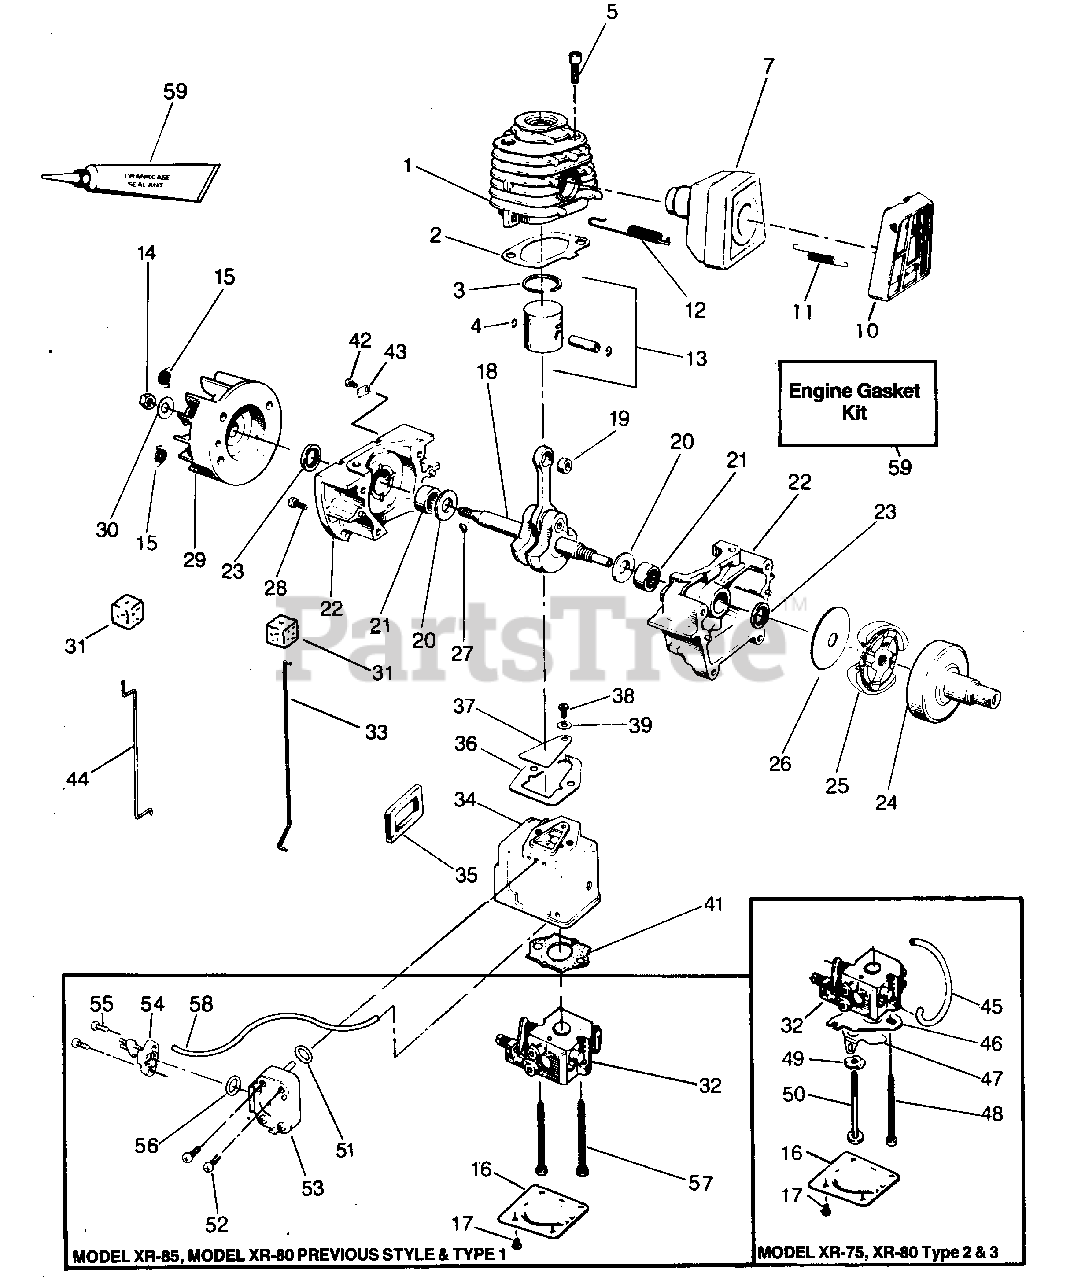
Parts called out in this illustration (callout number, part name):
1	Cylinder
1	Model XR-80,XR-85
1	Model XR-75
2	Gasket - Cylinder
3	Piston Ring
3	Model XR-85, XR-80 Type 1 & 2
3	Model XR-80 - Type 3
3	Model XR-75
4	Retainer - Wrist Pin
5	Screw #1/4 - 20 x 3/4" - Hex Soc. Hd. - Cylinder
10	Guard - Muffler
11	Spring - Muffler Guard
12	Spring - Muffler Attachment
13	Piston Kit (Inc. #3, 4 & Pin)
13	Model XR-85,XR-80 Previous Style & Type 1 & 2
13	Model XR-80 - Type 3
13	Model XR-75
14	Nut - Flywheel
15	Spring - Starter Dog
16	Cover - Carburetor Case
16	Model XR-80,XR-85
17	Screw - #8 - 18 x 9/16" - Pan Hd Carburetor Case Cover
18	Crankshaft & Rod Ass'y.
18	Model XR-75,XR-85, XR-80 Previous Style & Type 1, 2
18	Model XR-80 - Type 3 Only
19	Bearing - Wrist Pin
19	Model XR-75,XR-85, XR-80 Previous Style & Type 1, 2
19	Model XR-80 - Type 3 Only
20	Washer - Thrust - Crankcase
21	Bearing - Crankshaft
22	Crankcase Ass'y. (Inc. #21, 23 & Qty. 1 of #28)
23	Seal - Crankcase
24	Drum & Coupling Assembly
25	Kit - Clutch Assembly (Inc. Clutch Washer) - See Service Ref. 1 & 7
26	Kit - Clutch Washer
27	Key - Flywheel
28	Screw - #10 - 24 x 5/8" Fil. Hd. - Crankcase
29	Flywheel Assembly (Inc. #15)
30	Washer - Flywheel
31	Boot - Throttle/Choke Wire
32	Carburetor (See Service Ref. 2 - for Model XR-75 only)
33	Throttle Wire
33	Model XR-75, XR-80 Type 2 & 3
33	Model XR-85, XR-80 - Previous Style & Type 1
34	Carburetor Case
34	Model XR-85, XR-80 Previous Style & Type 1
34	Model XR-75, Model XR-80 - Type 2 & 3
35	Seal - Carburetor Case
36	Gasket - Carburetor Case to Crankcase
37	Reed Valve
38	Screw - #6 - 19 x 5/16" - Pan. Hd. - Reed Valve
39	Washer - Reed Valve Screw
41	Gasket - Carburetor
42	Screw - #8 - 32 x 5/16" - Choke Wire Clamp
43	Clamp - Choke Wire
44	Choke Wire -
44	Model XR-80 - Type 2 & 3
45	Fuel Line - Carburetor
45	Model XR-75, XR-80 - Type 2
45	Model XR-80 - Type 3
46	Guide - Plate Choke Wire
46	Model XR-80 - Type 2 & 3
47	Shutter - Choke
48	Screw - #10 - 24 x 1-7/8" - Carburetor
49	Washer - Wave
50	Screw - #10 - 24 x 2-1/8" - Carburetor Shoulder
51	O-Ring (Orifice)
52	Screw - #8 - 18 x 1" - Accumulator
53	Accumulator Assembly (Inc. #51 & 54)
54	Cap Assembly - Accumulator (Inc. #56)
55	Screw - #8 - 16 x 9/16"
56	O-Ring (Accumulator Chamber)
57	Screw - #10 - 24 x 2-1/4" - Fil. Hd. - Carburetor
58	Fuel Line - Carburetor
59	Engine Gasket Kit
